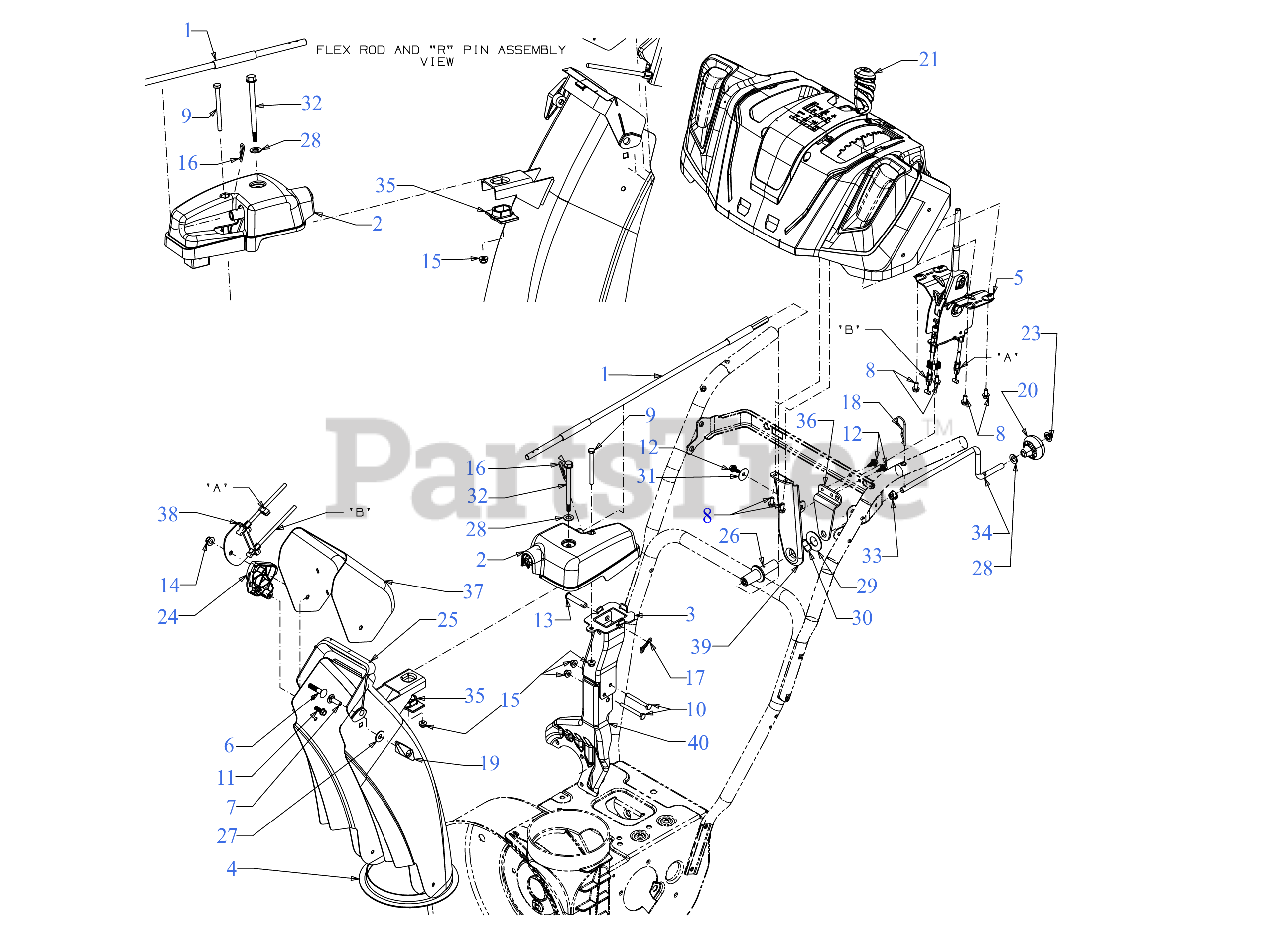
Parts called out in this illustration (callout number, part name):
1	CHUTE CONTROL SHAFT
2	GEARBOX ASSEMBLY
5	2-WAY STEEL CHUTE CONTROL ASSEMBLY
6	CARRIAGE BOLT 5/16-18 x 1.50
7	CARRIAGE BOLT 5/16-18 x 1.00
8	HEX SCREW 1/4-15 x .50
9	SCREW 1/4-20 x 3.0 GR5
10	SCREW 1/4-20 x 2.25 GR5
11	SCREW 1/4-15 x .750
12	SCREW 1/4-20X.625
13	CLEVIS PIN 3/8 x 1.87
14	FLANGE LOCK NUT 5/16-18
15	FLANGE LOCK NUT
16	INTERNAL COTTER PIN-1/2 DIA
17	BOW TIE COTTER PIN 1/4-5/16
18	INTERNAL COTTER PIN
19	WING KNOB NUT
20	SHIFT KNOB
21	PTO HANDLE GRIP .355 ID
23	PUSH NUT
24	CHUTE TILT GUIDE
25	UPPER CHUTE ADAPTER
26	CHUTE ROD COUPLER
27	FLAT WASHER
28	FLAT WASHER
29	FLAT WASHER
30	WAVE WASHER .785X1.00X.012
31	FLAT WASHER
32	SHOULDER SCREW
33	BUSHING .380 ID
34	CHUTE CRANK (POWDER BLACK)
35	HELICAL GEAR CHUTE ADAPTER
36	ROD SUPPORT BRACKET
38	CABLE BRACKET GUIDE (POWDER BLACK)
39	CHUTE CONTROL BRACKET
